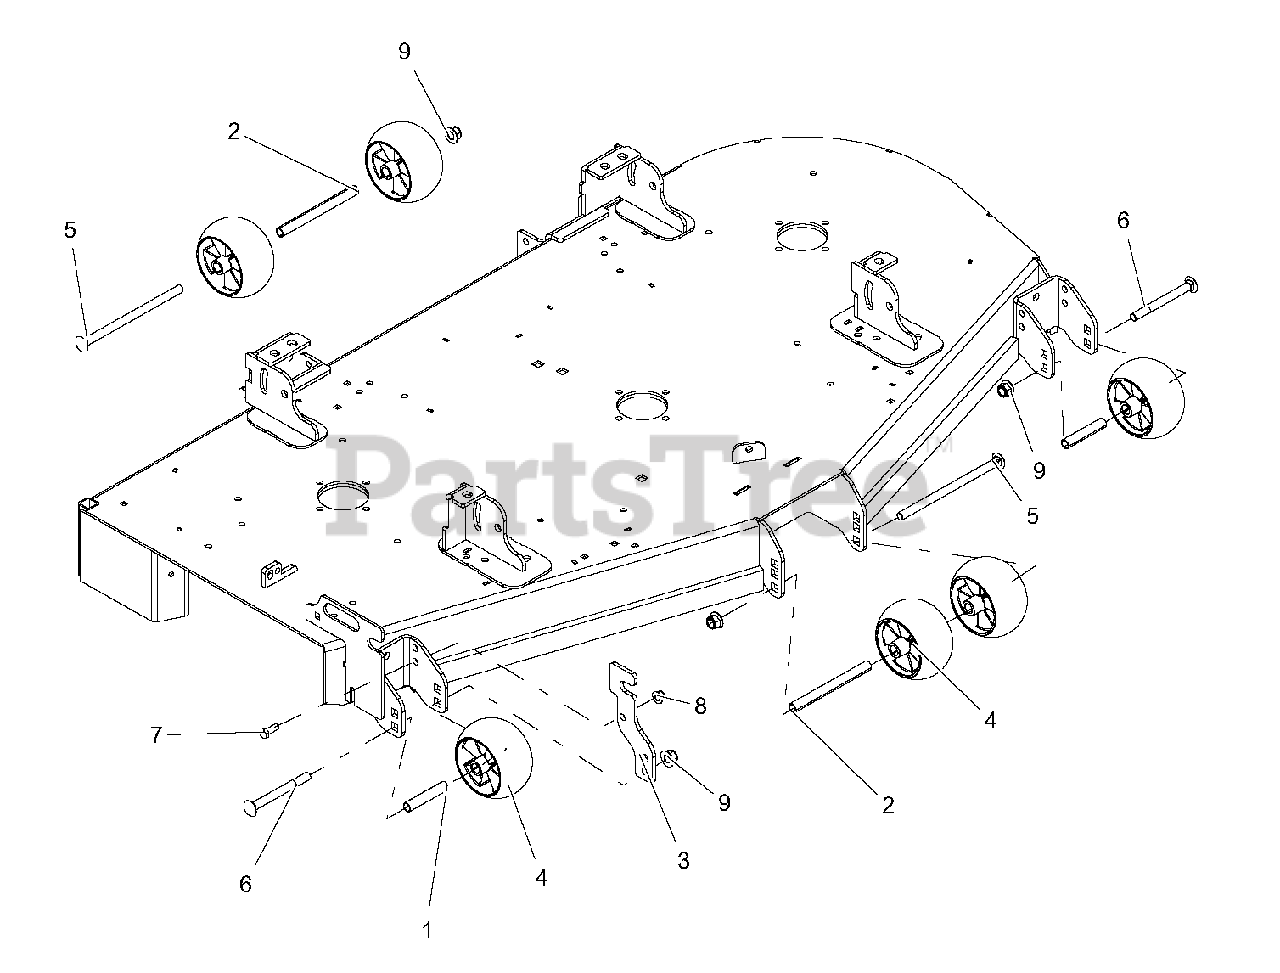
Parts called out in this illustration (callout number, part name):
1	SPACER, .510X.625X3.35
2	SPACER, .510X.625X6.70
3	CHUTE STORAGE BRACKET-RED
4	ANTI-SCALP WHEEL - 5X3 CTR
5	@BLT-RDHDSQNK .50-13X8.50 Y
6	BLT-RDHDSQNK .50-13X5.00 G5
7	BLT-HEX .38-16X1.00 GR5 YWZC
8	NUT-LK-NYL-FLG .38-16 YWZC
9	NUT-LK-NYL-FLG .50-13 YWZC
